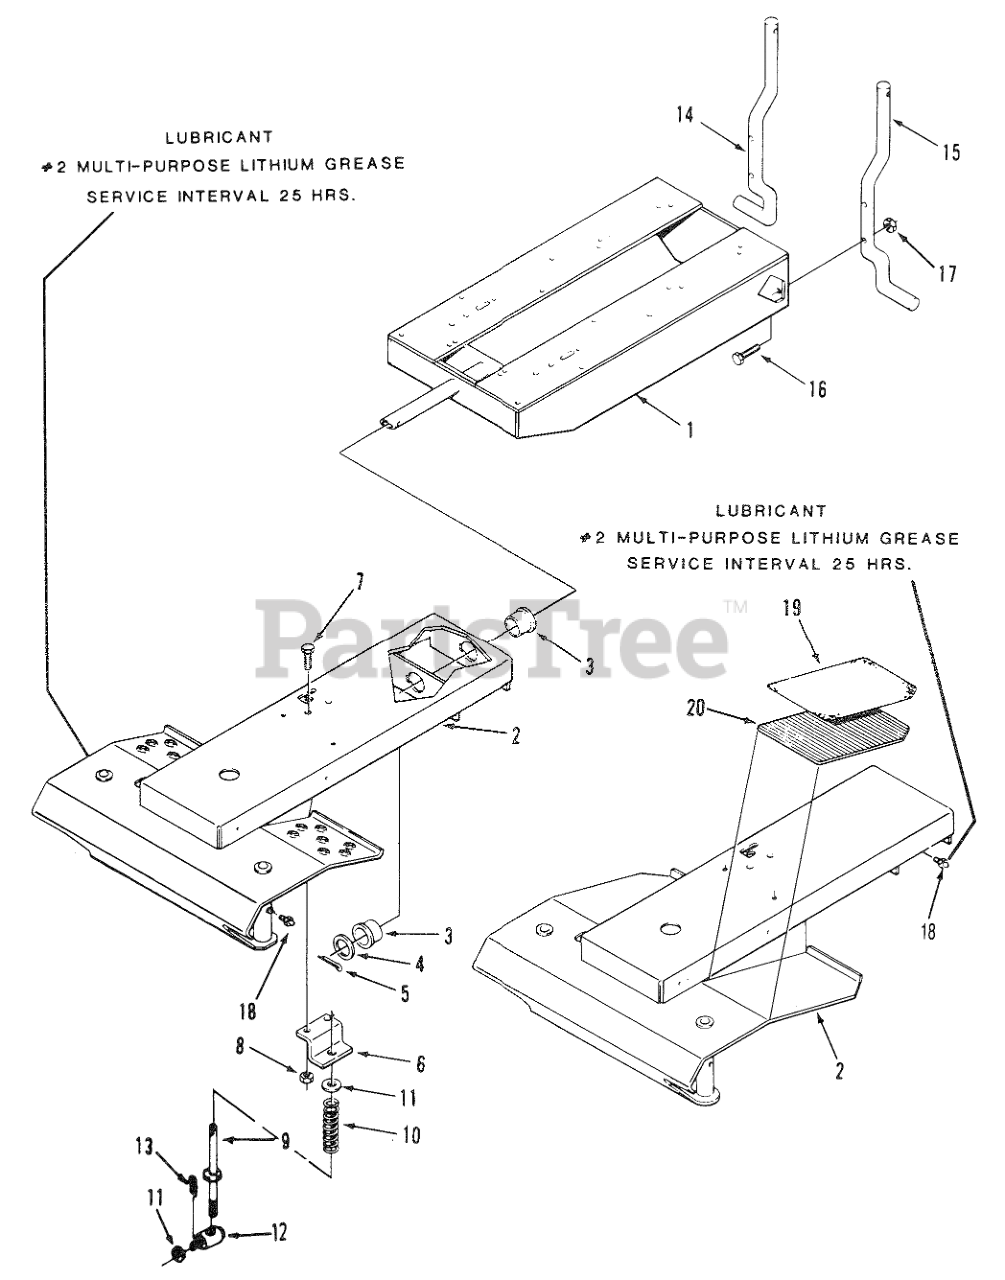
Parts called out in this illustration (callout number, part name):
1	ASS'Y-FRAME REAR R
2	ASSY FRONT FRAME R
3	BEARING FLANGE
4	WASHER
5	Pin-Cotter
6	BRACKET R
7	Bolt
8	NUT
9	ASSY ROD
10	SPRING-COMPRESSION
11	Washer 3/8 SAE
12	TRUNNION
13	Cotter Pin
14	REAR ROD RH B
15	REAR ROD LH B
16	Bolt
17	LOCKNUT 5/16-18GR.B
18	Grease Zerk
19	PAD FOOTREST RH
20	PAD FOOTREST RH
